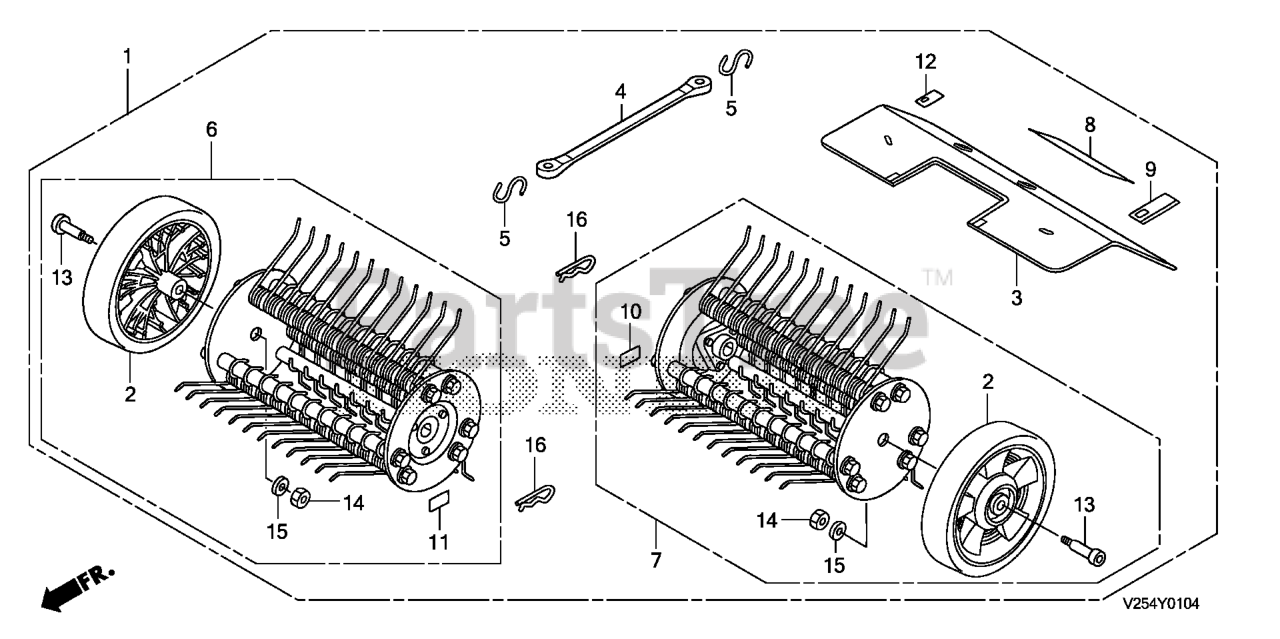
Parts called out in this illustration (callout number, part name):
1	DE-THATCHER KIT
2	WHEEL, RR.
3	FENDER, DE-THATCHER
4	STRAP, FENDER (NOT AVAILABLE)
5	HOOK, S (NOT AVAILABLE)
6	DE-THATCHER, R.
7	DE-THATCHER, L.
8	LABEL, TINE DANGER (ENGLISH)
9	MARK, OIL LEVEL CHECK (ENGLISH)
10	DECAL, L. (NOT AVAILABLE)
11	DECAL, R. (NOT AVAILABLE)
12	MARK, DE-THATCHER NOTICE (ENGLISH)
13	BOLT, SHOULDER (3/8-16X1-1/2IN) (NOT AVAILABLE)
14	NUT, CENTERLOCK (3/8-16)
15	WASHER, LOCK (3/8IN) (NOT AVAILABLE)
16	PIN, LOCK (17MM)
